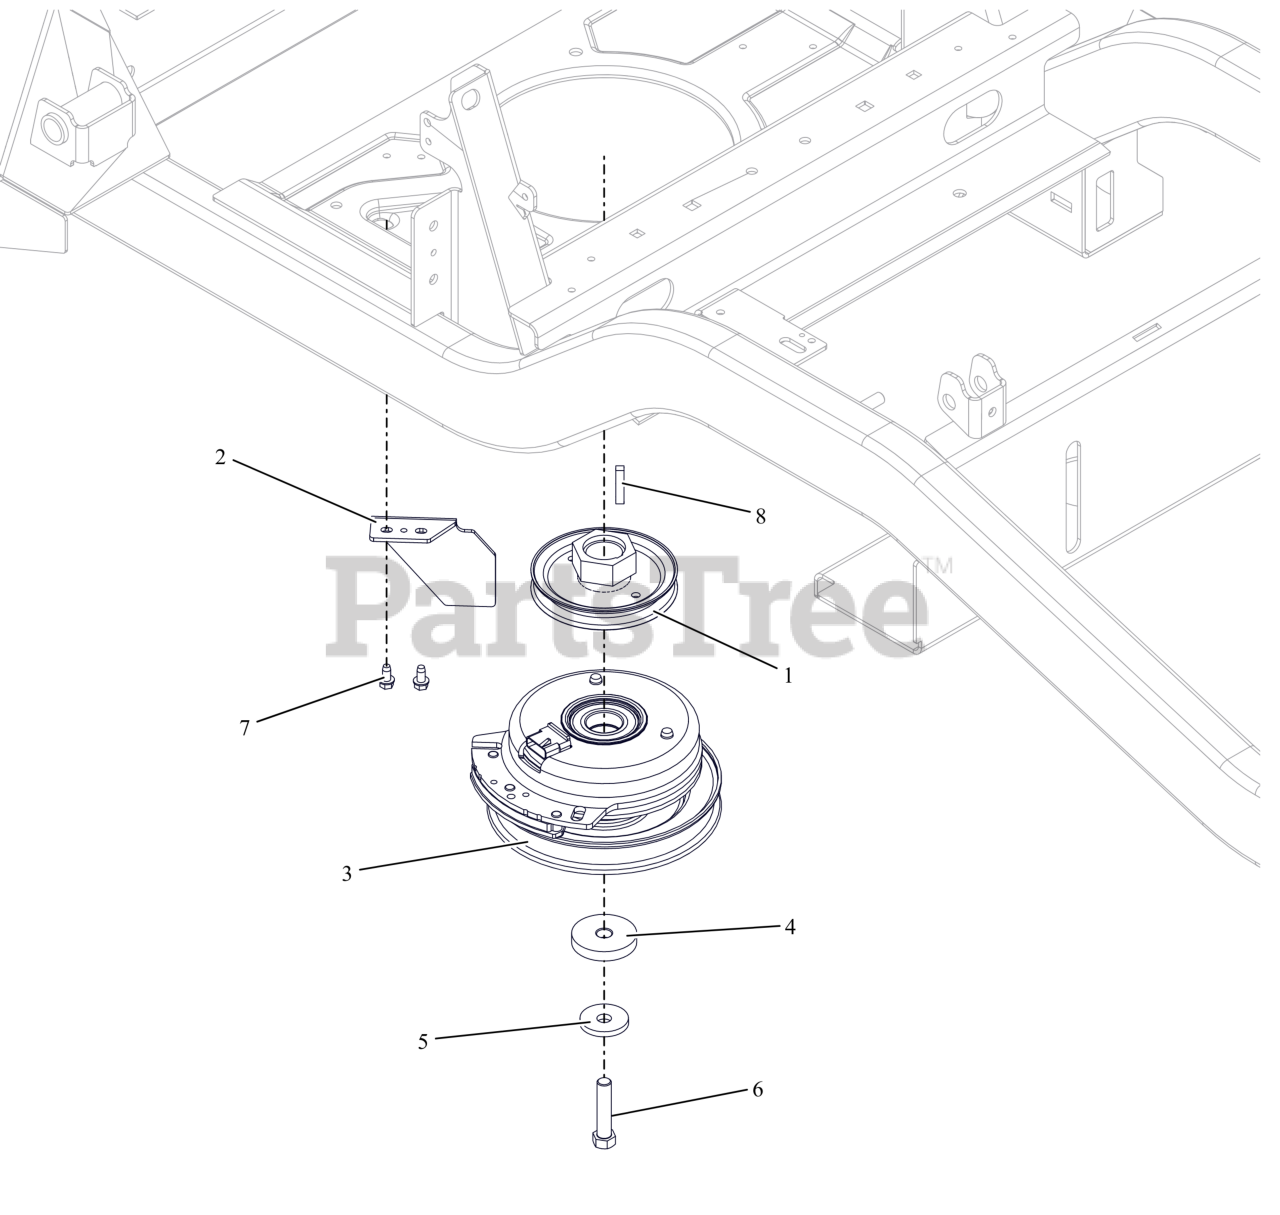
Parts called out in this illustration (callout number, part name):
1	WLDMT,PULLEY-4.50ODX1.127
2	BRKT, CLUTCH
3	CLUTCH- WARNER 1.125 PT-ZX
4	SPACER, .474/.459X2.00X.350
5	WASHER, 7/16" SPRING DISK
6	BLT, HEX .44-20X2.00 G8 ZCC NT
7	SCR-TAP .25-20X.50 HWH ZCC
8	KEY-SQ .25 X 1.25 X .25 SAE
